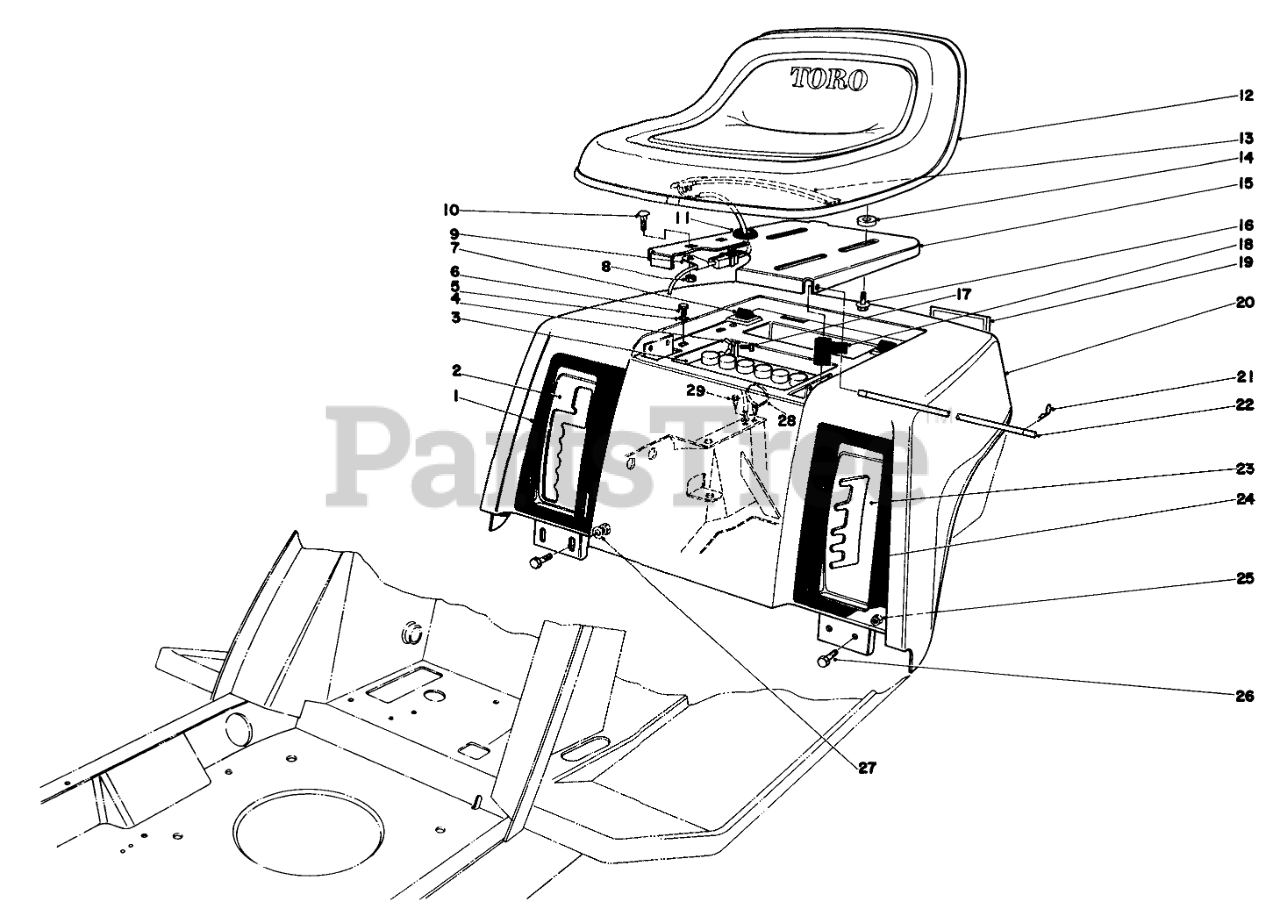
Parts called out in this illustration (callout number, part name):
1	Decal-Transmission
2	DETENT PLATE B
3	Battery
4	NUT-WING
5	WASHER
6	SCREW-HWHTF
7	SEAT BUMPER
8	NUT-KEPS
9	CLAMP
10	SCREW-CARR
11	GROMMET
13	SWITCH-SEAT
14	SPACER-PIN, MOUNTING
15	SEAT SUPPORT R
16	SCREW-HHF
17	SCREW-HH
18	BOOT-TERMINAL
19	REFLECTOR
20	Rear Body (Incl. Ref. #1 & 24)
21	PIN-COTTER
22	PIVOT-SEAT
23	Quadrant Height of Cut
24	Decal Height of Cut
25	NUT-LOCK, CONE
26	SCREW-HH
27	WASHER-PLAIN
28	TIE-MOUNT, PUSH
29	SCREW-HWHTF
